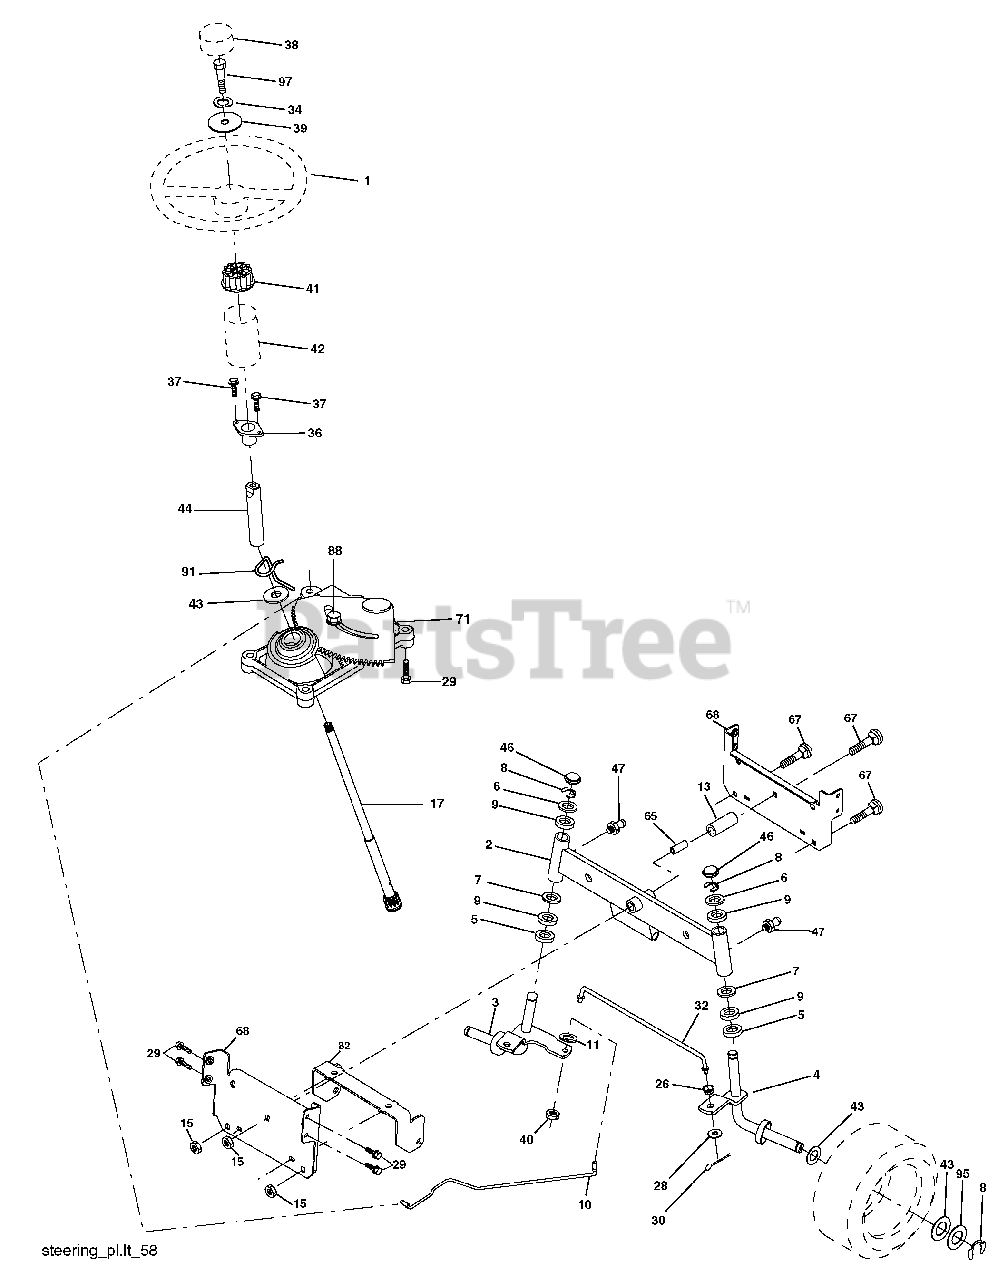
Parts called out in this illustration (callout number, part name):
1	Wheel Steering Auto Black
2	Axle Asm Front
3	Spindle Asm Lh
4	Spindle Asm Rh
5	Bearing Race Thrust Harden
6	Washer 25/32 x 1 5/8 x 16 Ga.
7	Washer 27/32 x 1 1/4 x 16 Ga.
8	Ring Klip #t5304-75
9	Bearing Col Strg Blk
10	Link Drag Extended
11	Lockwasher
13	Spacer Bearing Axle Front
15	Hex Flange Lock
17	Shaft Asm Strg
26	Bushing Rod Tie Blk Lt
28	Washer 13/32 x 7/8 x 16 Ga.
29	Screw 3/8-16 x 3/4
30	Pin
32	Rod Tie Wire Form 19 75 Mech
34	Washer Lock Hvy 5/16
36	Bushing Strg 5/8 Id Dash
37	Screw TT #10-32 x 5 x 3/8 Flange
38	Insert Cap Strg
39	Washer 11/32 ID x 2-3/8 OD 12 Gr.
40	Nut Crownlock
41	Adaptor Wheel Strg .760
42	Boot Dash Steering
43	Washer 25/32 x 1 1/4 x 16 Ga.
44	Extension Steering
46	Cap Spindle Fr Top Blk
47	Fitting Grease
65	Spacer Brace Axle
67	Bolt Rdhd Sq 3/8-16 unc x 2-1/4
68	Brace Axle
71	Steering Asm
82	Bracket Susp Chassis Front
88	Bolt Shoulder 7/16-20
91	Clip Steering
95	Washer Hardened
97	Bolt 5/16-18 unc x 4" L Gr. 5
